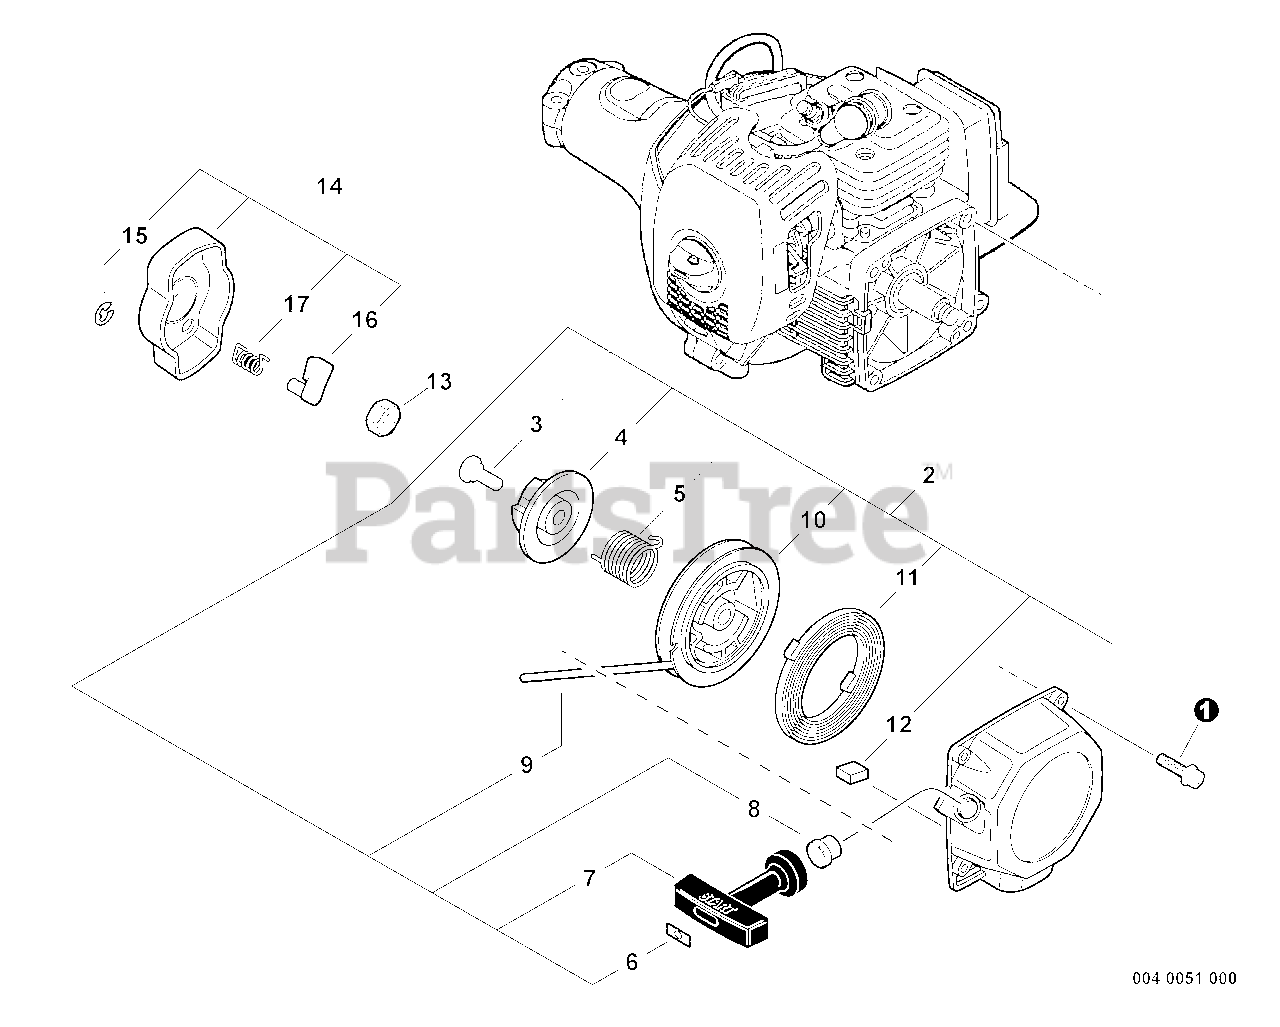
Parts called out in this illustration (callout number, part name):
1	SCREW - 5X16
2	STARTER ASSY
3	SCREW
4	PLATE, CAM
5	SPRING, DAMPER
6	RETAINER, ROPE
7	GRIP, STARTER
8	GUIDE, ROPE
9	ROPE, STARTER - 3X700
10	REEL, ROPE
11	SPRING, REWIND
12	NUT - 5 -- SQUARE
14	STARTER PAWL ASSY
15	RING, RETAINING - 4
16	PAWL, STARTER
17	SPRING, RETURN
